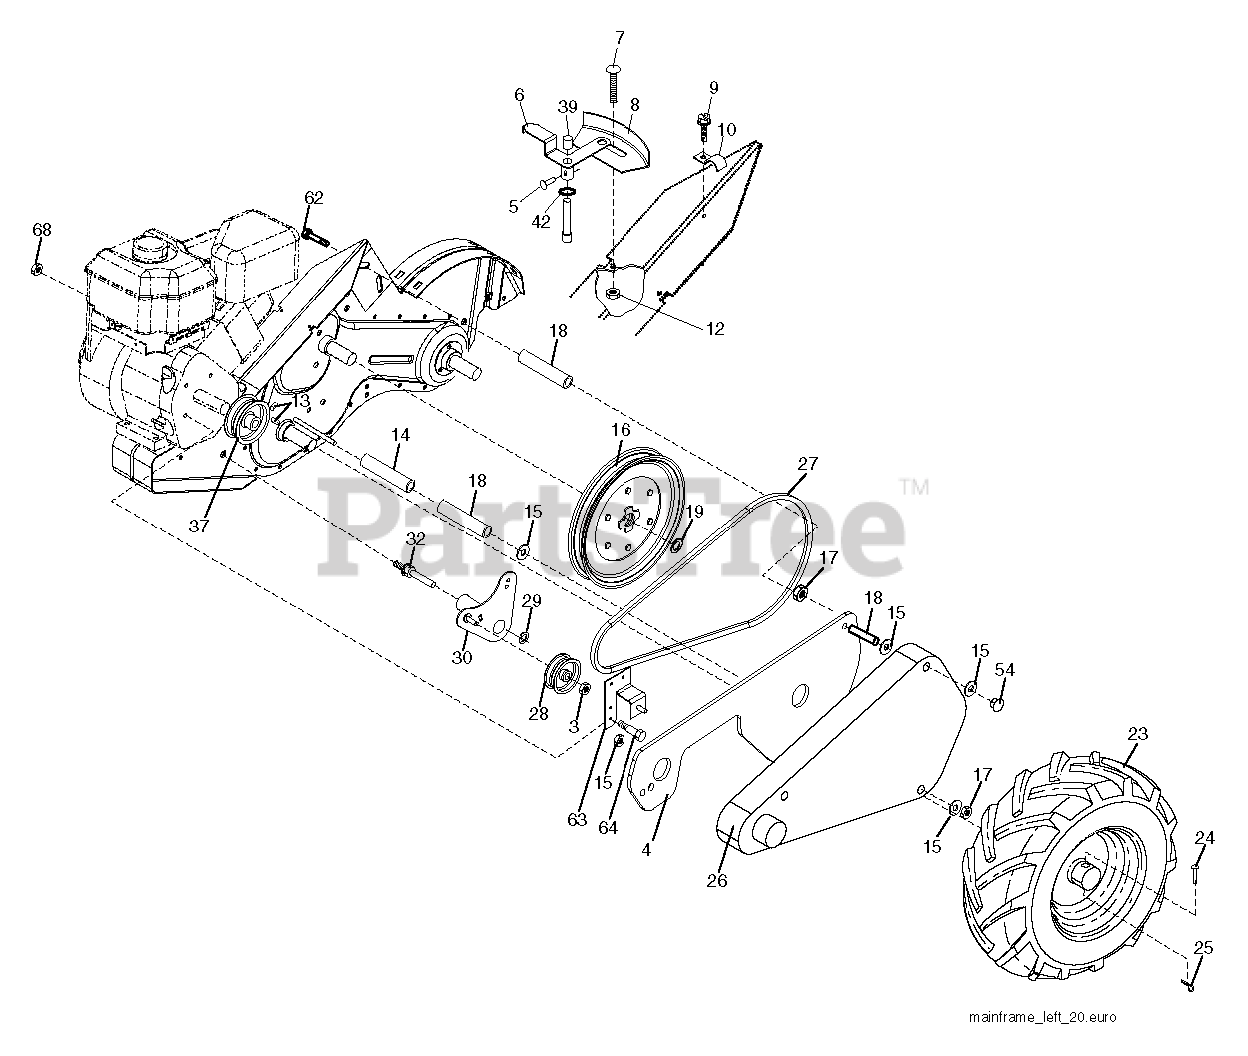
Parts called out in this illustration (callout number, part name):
3	NUT.HEX.3/8-16UNC
4	Shield, Inner Belt Guard RT
5	PIN.SPIROL.FLARED
6	LEVER ASM CRT
8	PANEL.INDICATOR.SHIFT.BLACK
9	TAPPING SCREW
10	CONDUIT.CLIP.PLATED
12	NUT
14	SPACER-SPLIT.327 X .42
15	WASHER
16	SHEAVE, TRANSMISSION
17	NUT
18	SPACER SPLIT
19	RETAINING RING LT
23	VALVE STEM LT
23	RIM 2.75 X 8.0 X 1"ID.TILLER
23	TIRE.16X4-8.CHEVRON.TILLER
25	SPRING TI
26	GUARD.BELT.TILLER.8HP.ORANGE
27	BELT, DRIVE
28	PULLEY-IDLER TI
30	BRACKET.ASM.IDLER.BLACK
32	SHAFT, IDLER ARM
37	SHEAVE, ENGINE
39	CAP.PLUNGER.BLACK
62	BOLT 5/16-18X4 1/2
63	Bracket Asm Guard
